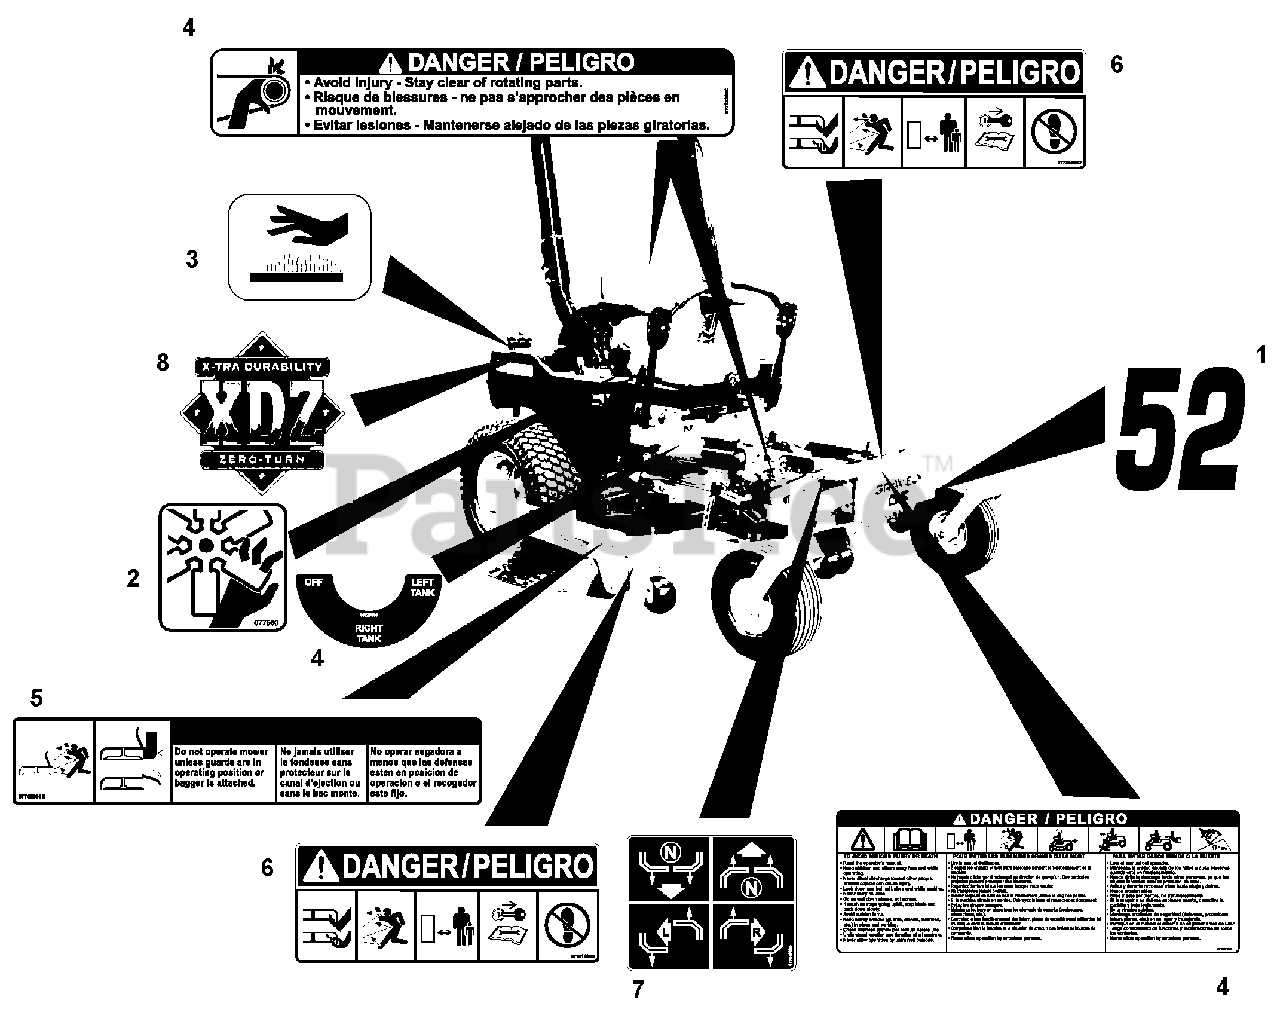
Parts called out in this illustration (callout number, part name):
1	Decal, 52 (992212)
2	Decal, Danger Fan
3	Decal, Hot Surface
4	Set, Decal – Common Danger/Fuel
5	Decal, Warning
6	Decal, Mower Pan Head Danger
7	Decal, Instructional
8	Decal, XDZ
